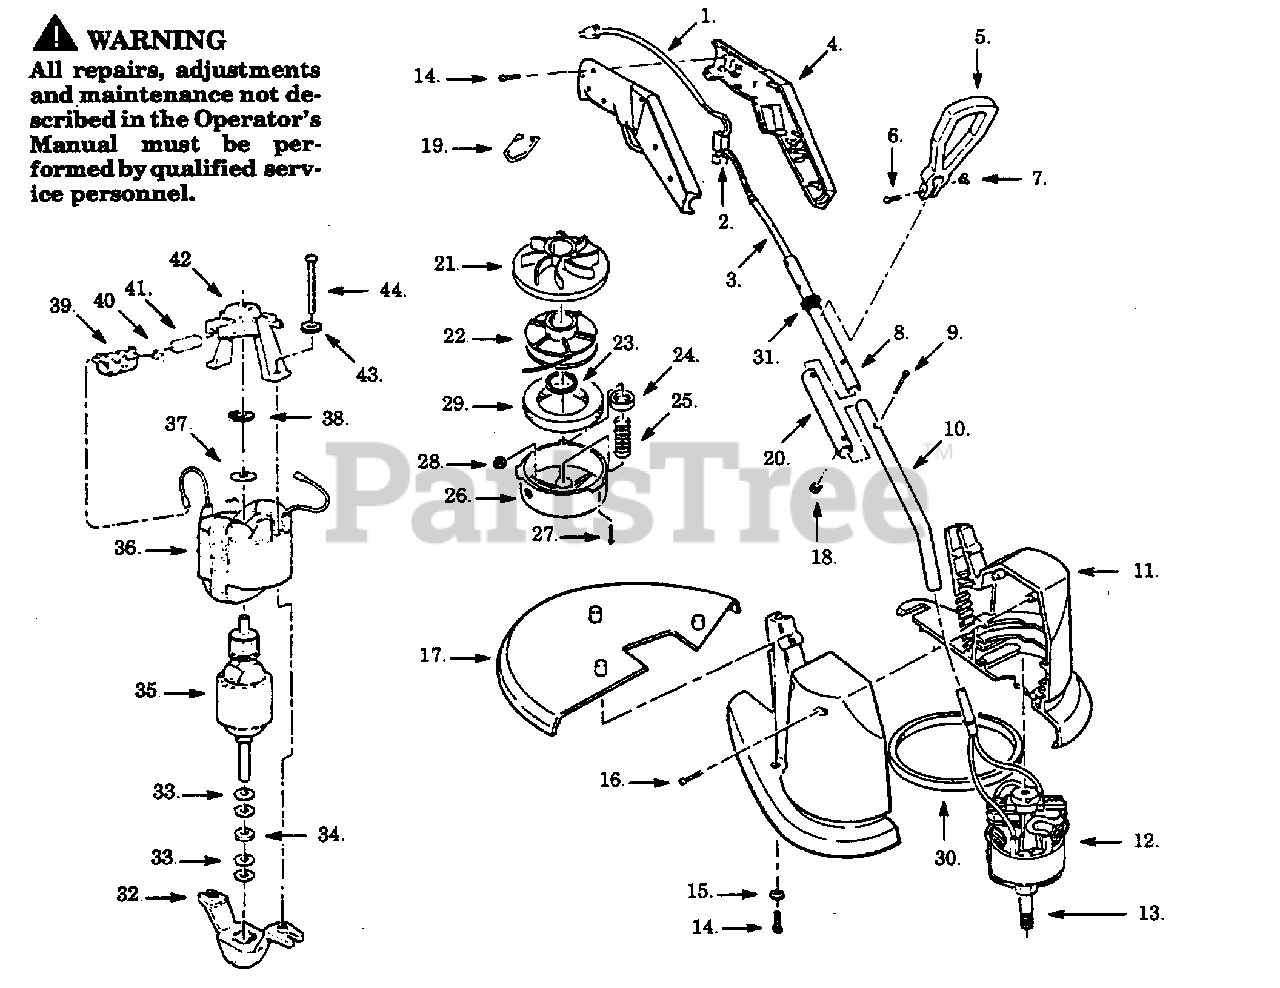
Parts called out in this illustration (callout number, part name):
1	Power Cord
4	R.H./L.H. Handle
5	Assist Handle
7	Wing Nut
8	Upper Tube
10	Lower Tube
11	Motor Housing
13	Shaft Adapter
17	Guard Ass'y.
20	Outer Tube
21	Rear Plate
22	Spool & Line
24	Adapter Nut
26	Hub Ass'y.
27	Cotter Pin
29	Foam Pad
32	Endbell Ass'y. (Drive)
34	Wave Washer
35	Armature Ass'y.
36	Field Ass'y.
38	Retaining Ring
39	Brush Holder
40	Brush Spring
42	Endbell Ass'y. (Brush)
43	Lockwasher
